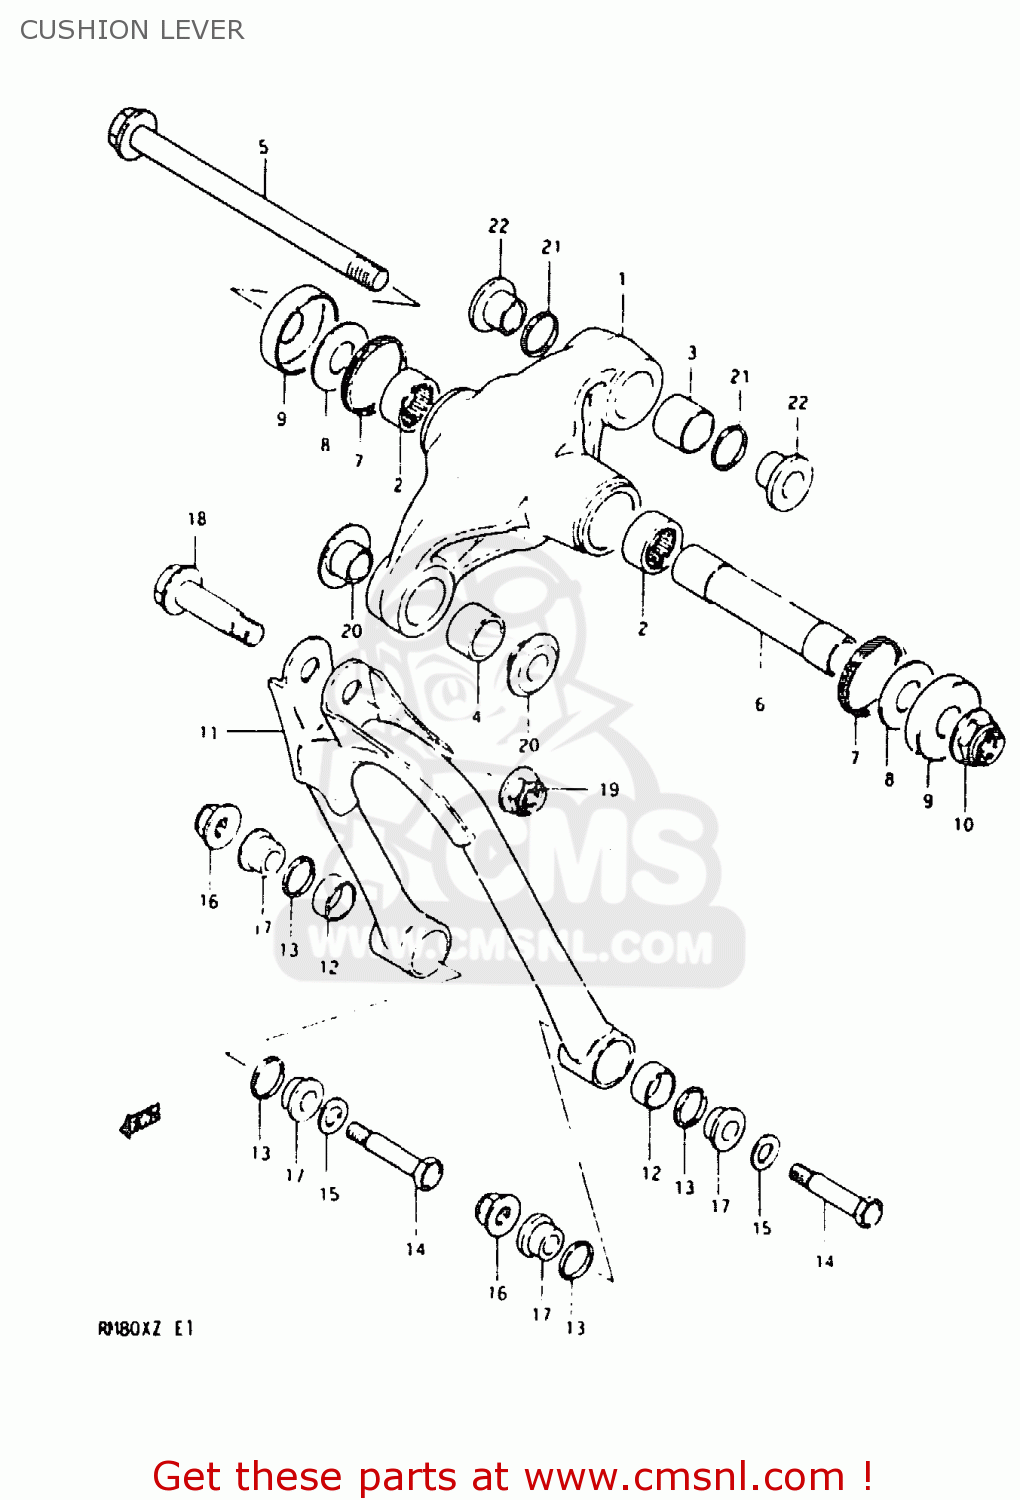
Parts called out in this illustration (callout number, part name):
1	LEVER SET,REAR CUSHION
2	BEARING(17X25X20)
3	BUSH,LEVER CUSHION UNIT
4	BUSH, FRONT
5	SHAFT,REAR CUSHION LEVER
6	SPACER,REAR CUSHION LEVER
7	DUST SEAL,RR CUSHION LEVER
8	THRUST WASHER
9	DUST COVER,REAR CUSHION
10	NUT 12MM
11	LEVER SET,REAR CUSHION
12	BUSHING
13	DUST SEAL,RR CUSHION LOD LWR
14	BOLT,REAR CUSHION LEVER
15	WASHER
16	NUT
17	SPACER,RR CUSHION ROD LWR
18	BOLT(10X40)
19	NUT
20	SPACER,REAR CUSHION,FRONT
21	DUST SEAL,LEVER CUSHION UNIT
22	SPACER,LEVER CUSHION UNIT
